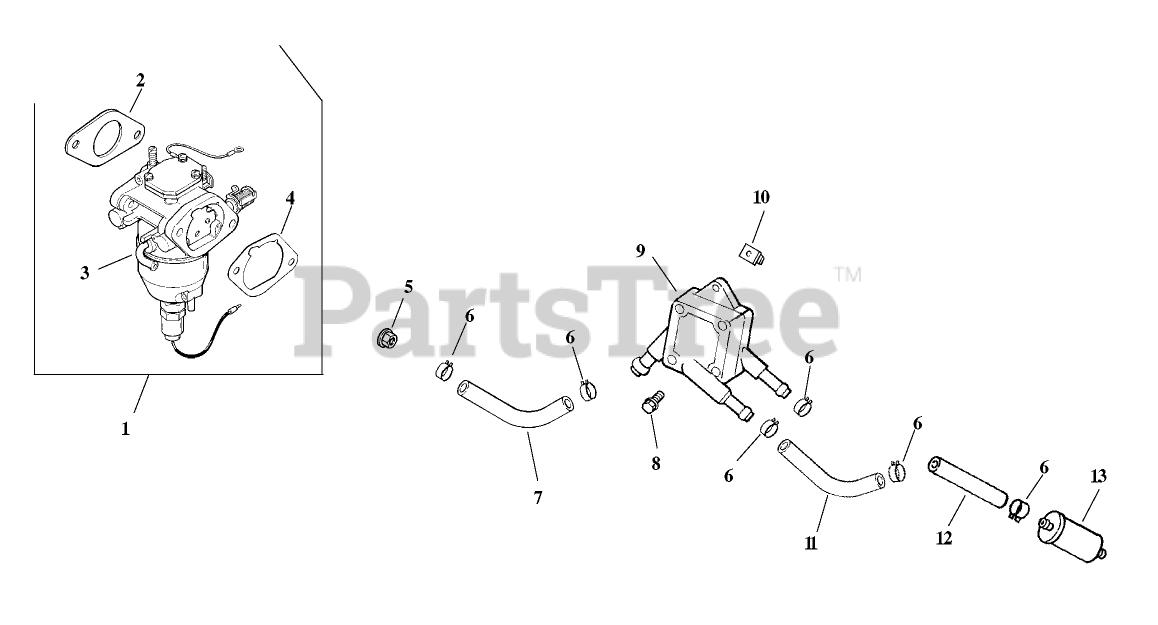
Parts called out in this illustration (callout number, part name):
1	Kit, carburetor w/gaskets (Includes 2-4)
2	Gasket-carburetor
3	Carburetor (Ref)
4	GASKET-BASE, AIR CLEANER
5	NUT-FLANGE (M6X1.0)
6	Clamp
7	Line, fuel
8	SCREW-TAP (M6X1.7X18)
9	PUMP-FUEL
10	Nut-Plastic
11	Line, fuel 10-1/2
12	Line, fuel 12-1/3"
13	Filter-Fuel
